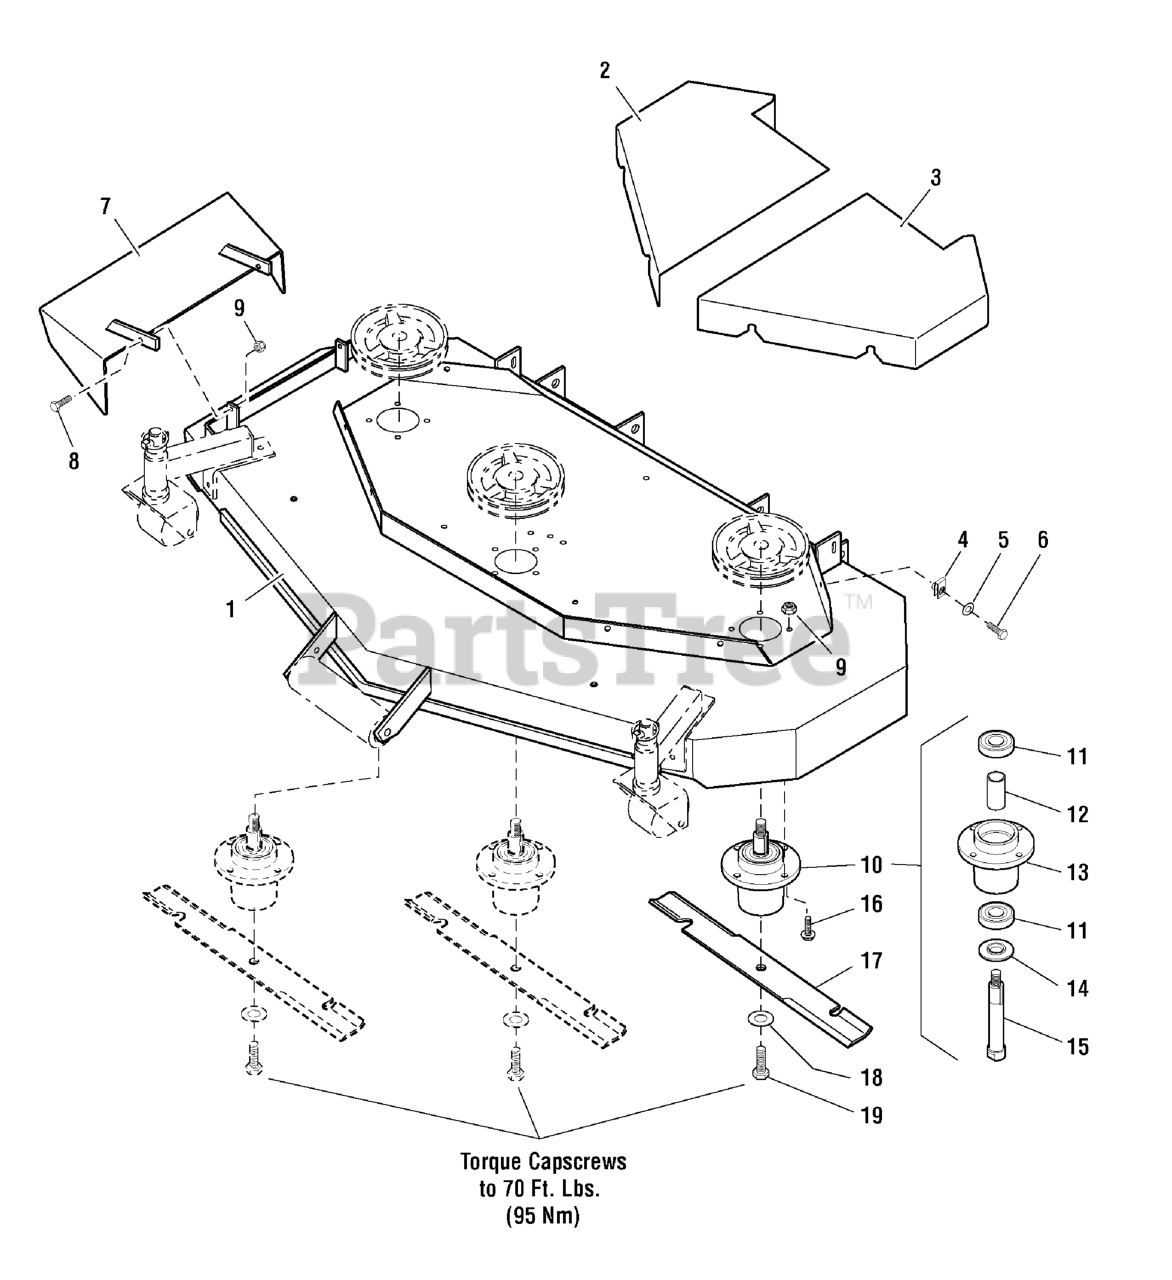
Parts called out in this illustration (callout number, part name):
1	DECK SHELL W/DECALS, 61"
2	SPINDLE COVER-RH
3	SPINDLE COVER-LH
4	BODY CLIP, 5/16-18-7GA MATERIAL
5	WASHER, 5/16" SAE
6	BOLT, 5/16-18 X 3/4 GD5
7	DISCHARGE CHUTE
8	BOLT, 5/16-18 X 1 GD5 YZ
9	NUT, 5/16-18 Hex Nylon Lock
10	* SPINDLE ASSEMBLY, Complete
16	BOLT, Flange Head, 5/16-18 x 1-1/4
17	MOWER BLADE, 21"
18	WASHER, 5/8" GRADE 8, YZ
19	BOLT, 5/8-11 X 1-3/4 GD8
